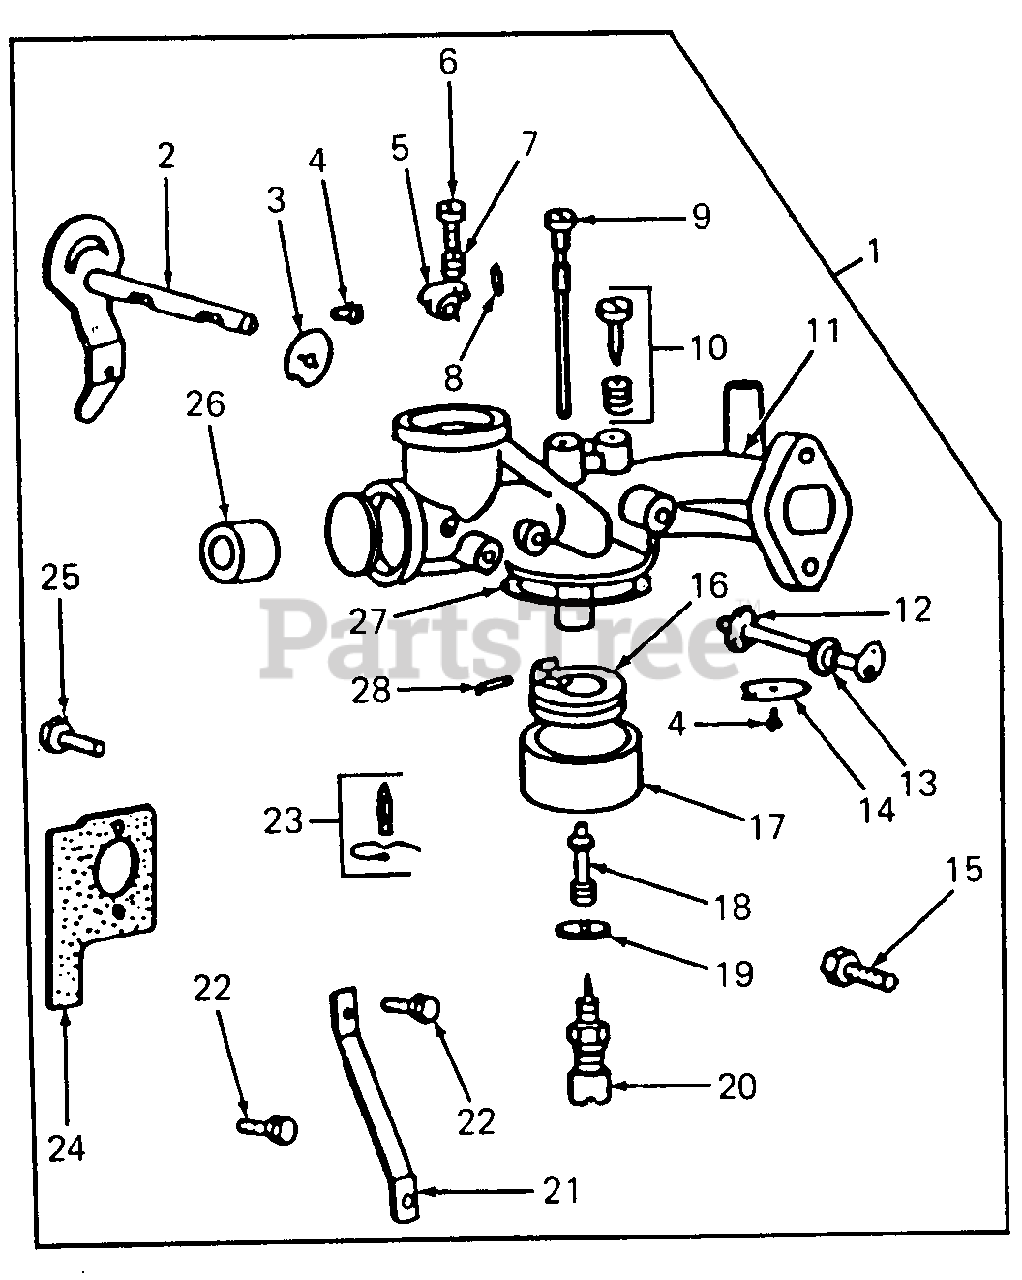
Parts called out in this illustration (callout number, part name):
1	Carburetor Assy
2	Shaft & Lever
3	Valve, Choke
4	Screw, Throttle & Choke Valve Mtg Sem
5	Stop, Throttle
6	Screw, Machine, Fill Hd 8-32 X 5/8
7	Spring, Throttle Adjustment
8	Pin, Throttle Stop
9	Nozzle, Carburetor
10	Valve Assy, Carburetor Idle
12	Seal, Throttle Shaft
13	Shaft & Lever, Throttle
14	Valve, Throttle
15	Screw, Control Casing to Screw
16	Float, Carburetor
17	Bowl, Float
18	Screw, Nozzle
19	Washer, Float Bowl
20	Valve, Needle
21	Bracket, Carburetor
22	Screw, Carburetor
23	Valve, Fuel Inlet
24	Gasket, Carburetor Mtg
25	Screw, Carburetor Mtg
26	Venturi, Carburetor Mtg
27	Gasket, Float Bowl
28	Pin, Float Hinge
